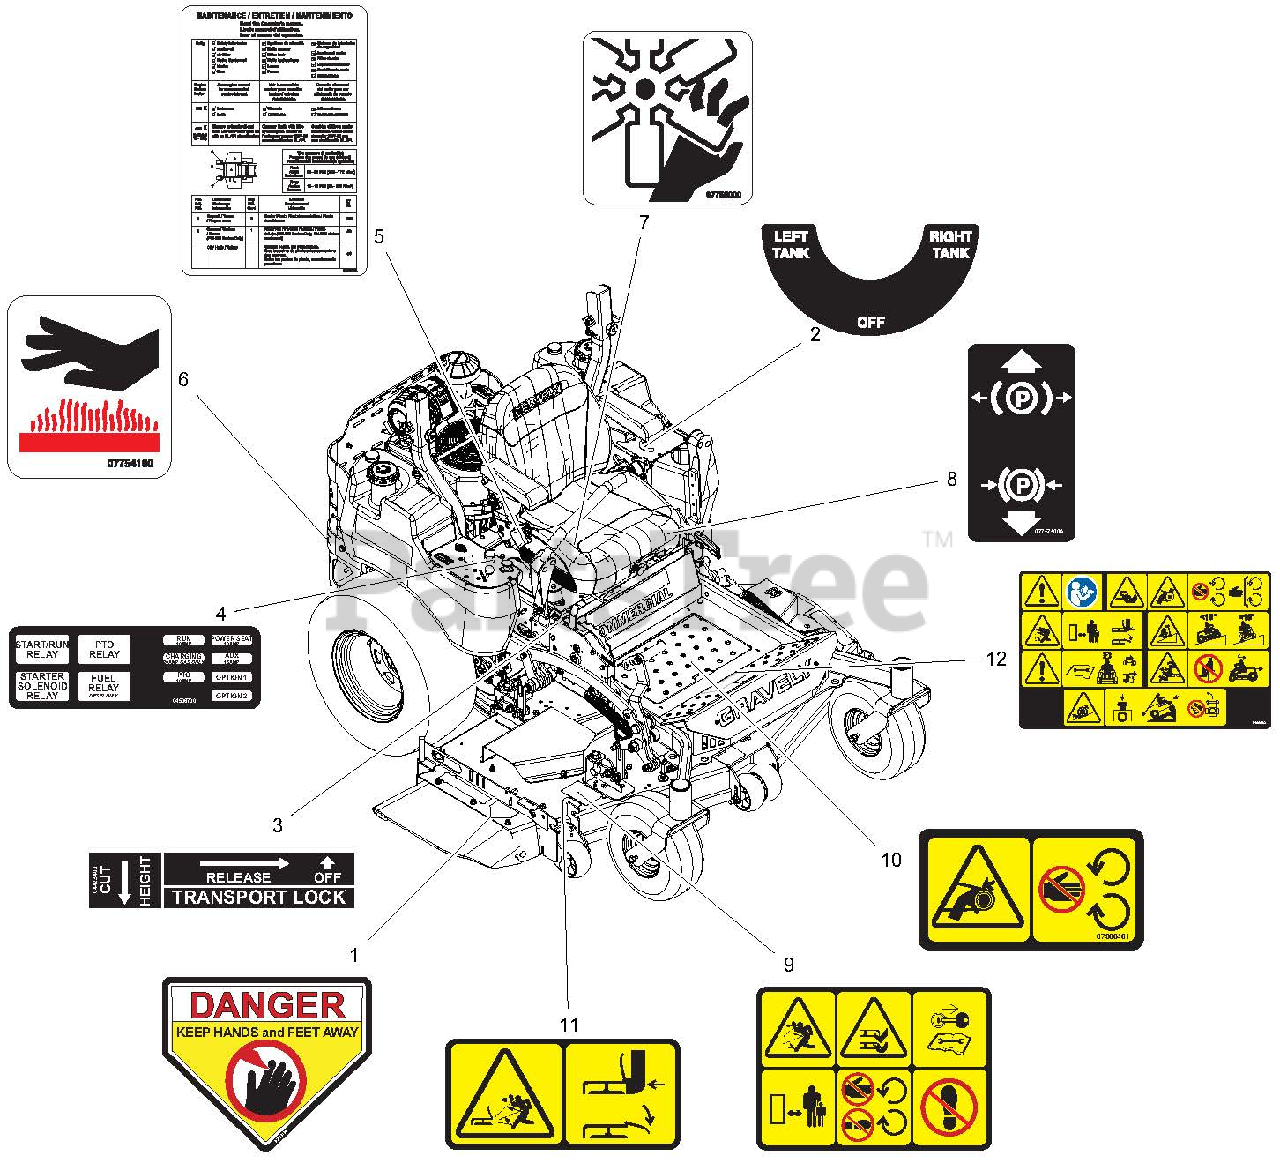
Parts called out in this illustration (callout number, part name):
1	DECAL, DANGER
2	DECAL, FUEL VALVE
3	DECAL, TRANSPORT LOCK INSTRUCT
4	DECAL, FUSE BOX
5	DECAL, MAINTENANCE
6	DECAL HOT SURFACE
7	DECAL, DANGER - FAN
8	DECAL, PARKING BRAKE LEVER
9	DECAL, SAFETY - MOWER DECK
10	DECAL, SAFETY - GUARDING
11	DECAL, SAFETY - DECK GUARDING
12	DECAL, MAIN SAFETY, COMMERCIAL
